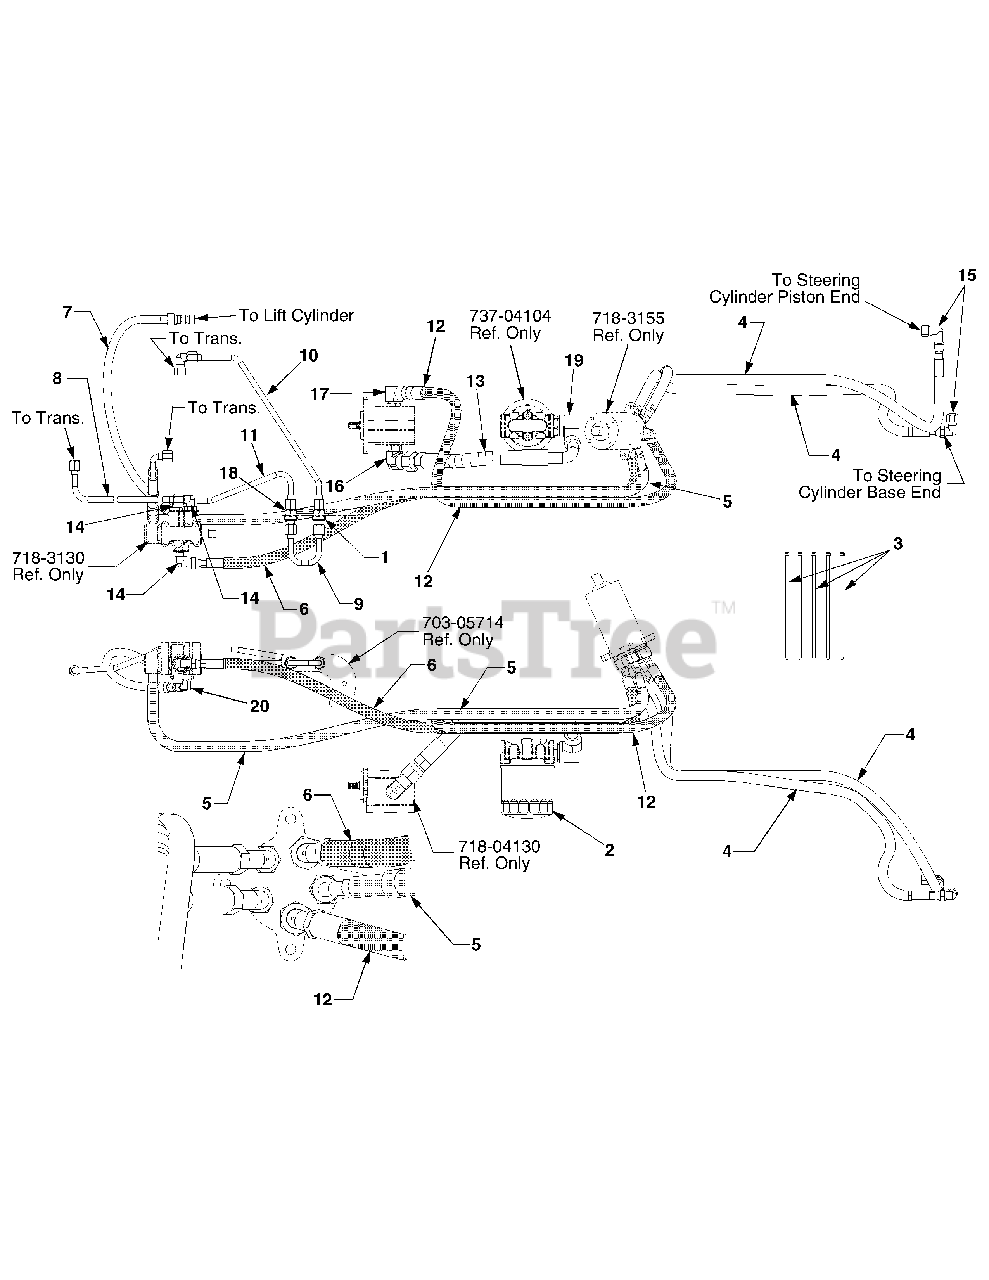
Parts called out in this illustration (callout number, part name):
1	Nut, Hex Jam, 9/16-18 GR5
2	Filter, Oil
3	Tie, Cable
4	Hose, Steering
5	Hose, Steering - Tank
6	Hose, Lift Inlet
7	Hose, Lift Cylinder
8	Tube, Cylinder Return
9	Tube, U Return
10	Tube, Return Tank
11	Tube, Return
12	Hose, Steering Pressure
13	Hose, Aux. Pump-Filter
14	Fitting, 90 Degree
15	Fitting, 90 Degree Swivel
16	Fitting, Elbow
17	Fitting, 90 Degree
18	Fitting, Bulkhead
19	Fitting, 90 Degree
20	Fitting, 90 Degree
